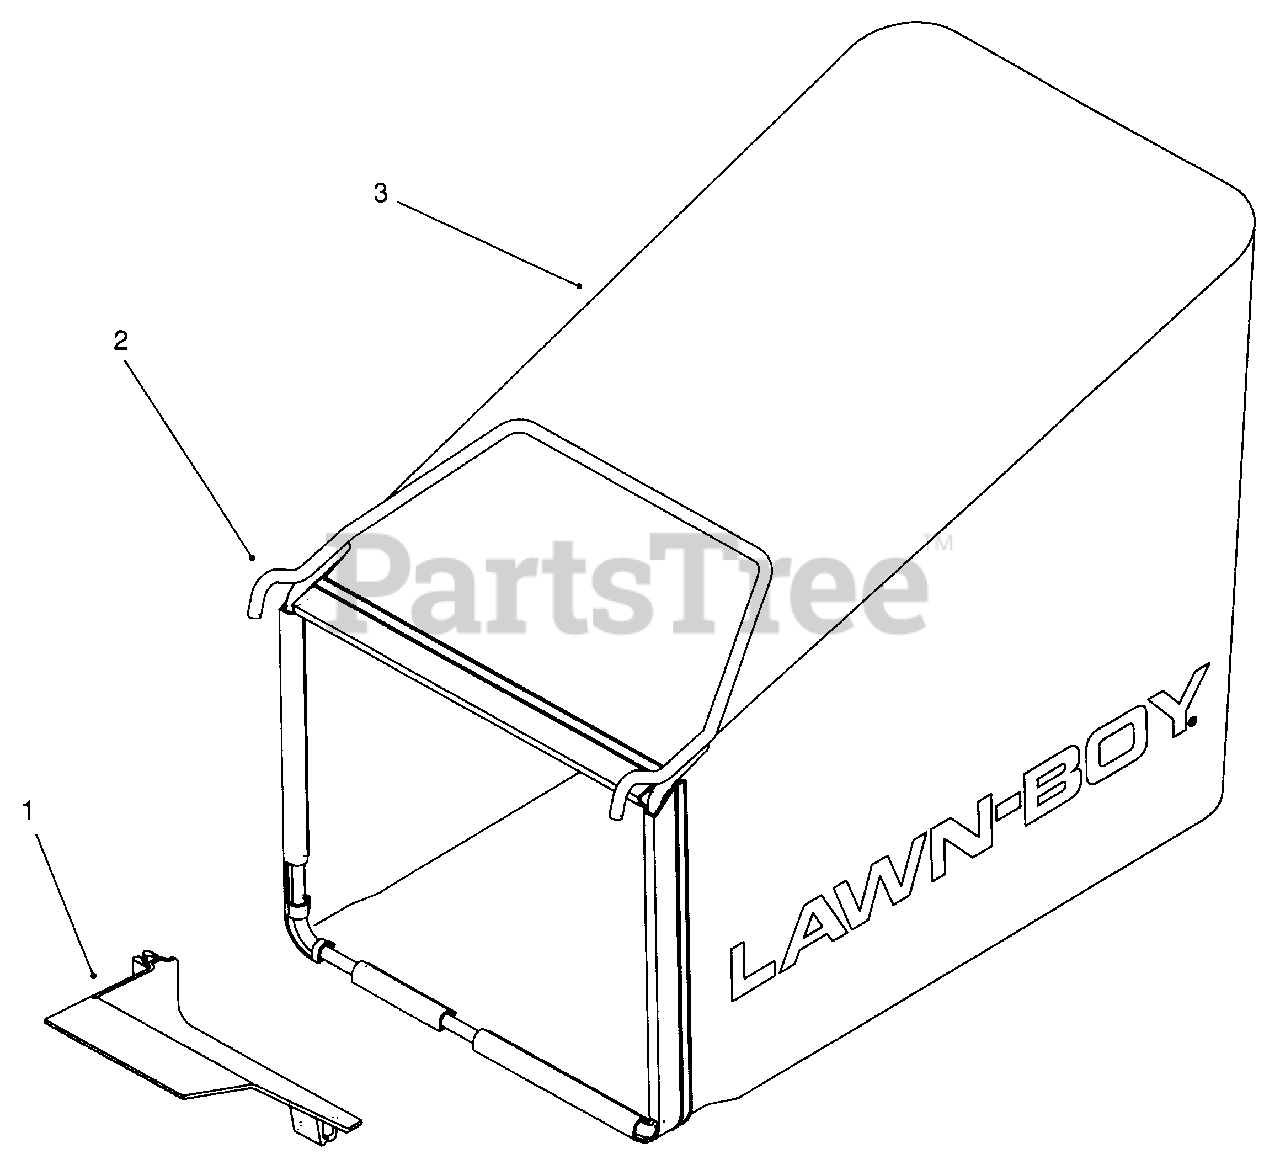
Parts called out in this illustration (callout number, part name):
1	Ramp-Grass Bag
2	Frame
3	Bag-Grass
